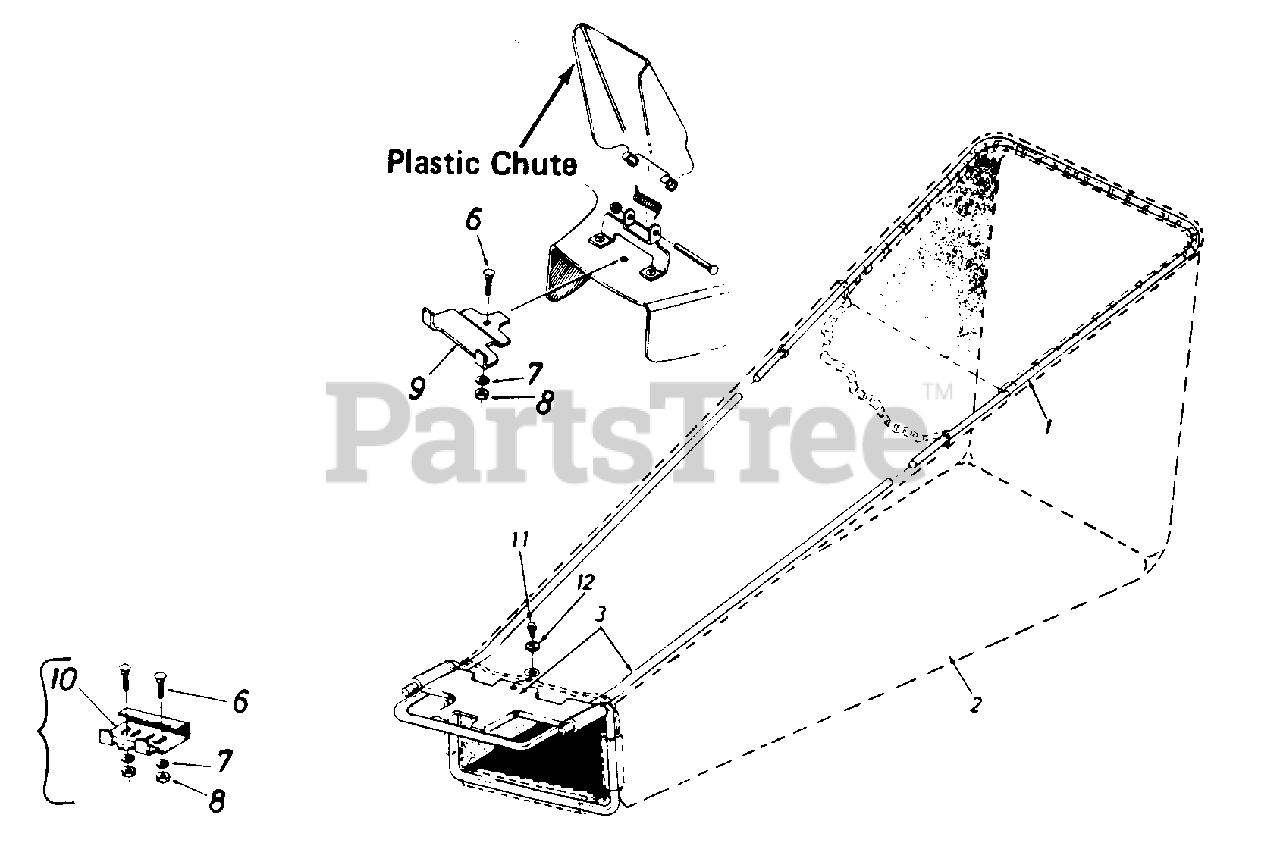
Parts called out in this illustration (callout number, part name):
1	Frame-Upper
2	Grass Catcher Bag
3	Frame- Lower
6	Carriage Bolt
7	Lock Washer 1/4" I.D.*
8	Hex Nut 1/4-20 Thd.1'
9	Adapter Plate
10	Adapter Plate
11	Self-Tap Scr. 1/4" x 1/2" Lg.
12	Bell-Wash. 1/4" I.D.
